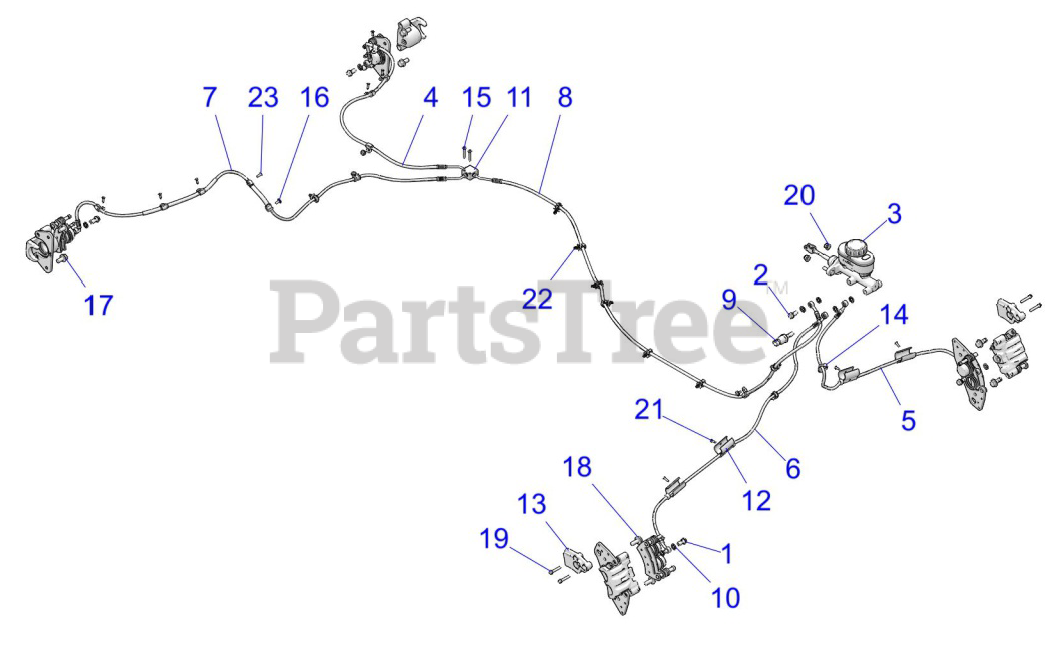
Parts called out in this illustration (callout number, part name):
1	BOLT-BANJO-10MMX1.00
2	BOLT-BANJO- 10MM X 1.25-6G
3	ASM-M/C-T-FLANGE-3/4 BORE
4	LINE-BRK-RL-41.1-45F-90SB-290J
7	LINE-BRK,RR,J
8	LINE-BRK-M/T-105.4-20B-30F-263
9	SWITCH-BRK-M10X1.25-DBL-SEALED
10	SEAL-STAT-O-3/8-70EP
11	FITTING-TEE-BRAKE
12	RETAINER-BRAKE LINE-1"
13	SCRAPER-BRAKE- FRONT
14	CLIP-ROUTING
16	SCREW(10)
17	BOLT-M10X1.25X20-HXFLG-OLV D
18	BOLT-M10X1.25X25-HXFLG-W/PATCH
19	SCR-HXFL-M6X1.0X35-W/PATCHLOK
20	NUT-M8X1.25-FLG-NYLOC-OLIVE D
21	POP RIVET(50)
22	CLIP-NYLON-C-FIR-TREE
